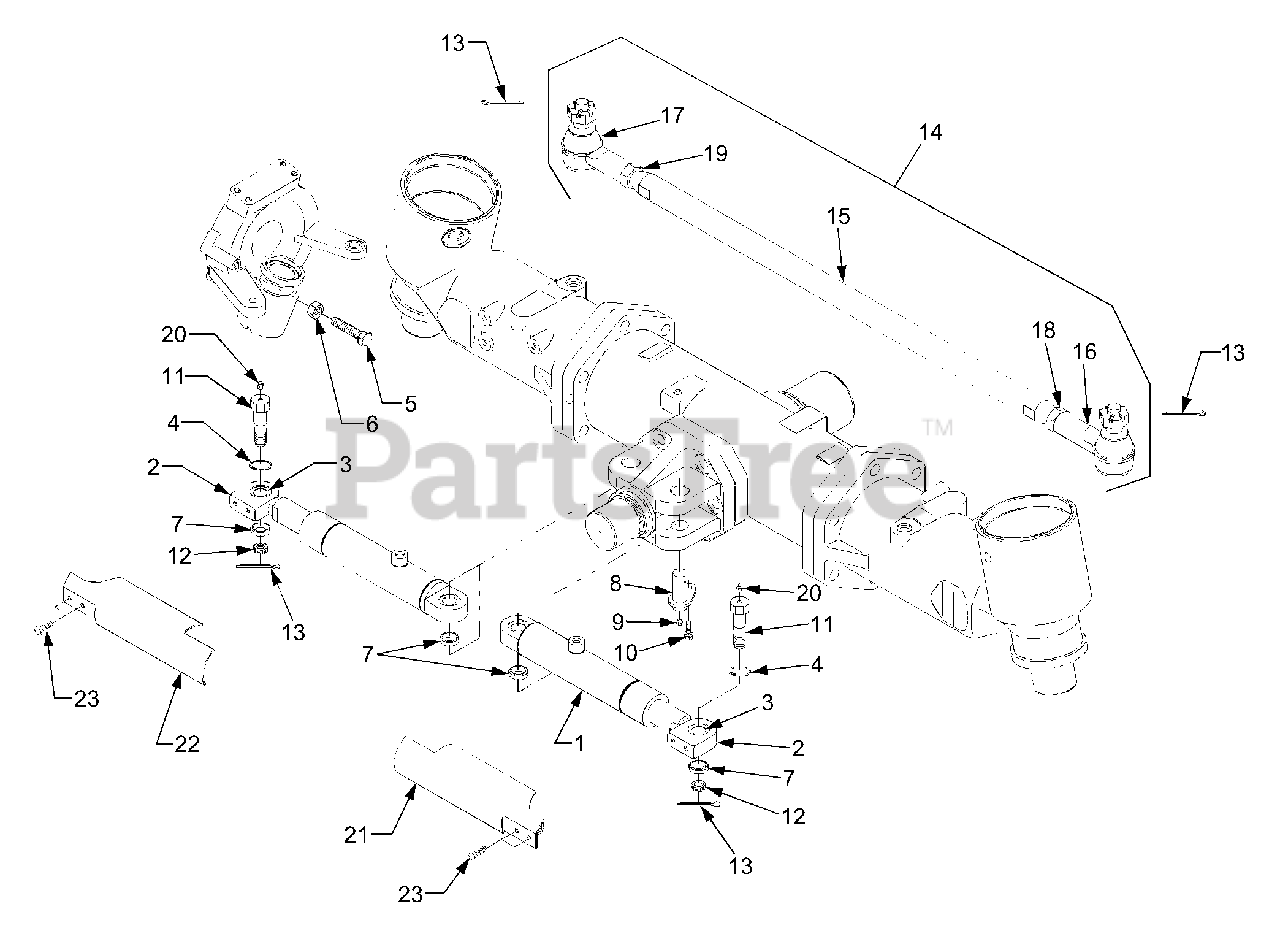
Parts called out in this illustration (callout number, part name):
1	Steering Cylinder Ass'y
8	Pin, Cylinder Support
14	Tie Rod Ass'y
15	Rod, Tie
16	Tie Rod End Ass'y (LH)
17	Tie Rod End Ass'y 2 (RH)
21	Cover, Cylinder (LH)
22	Cover, Cylinder (RH)
